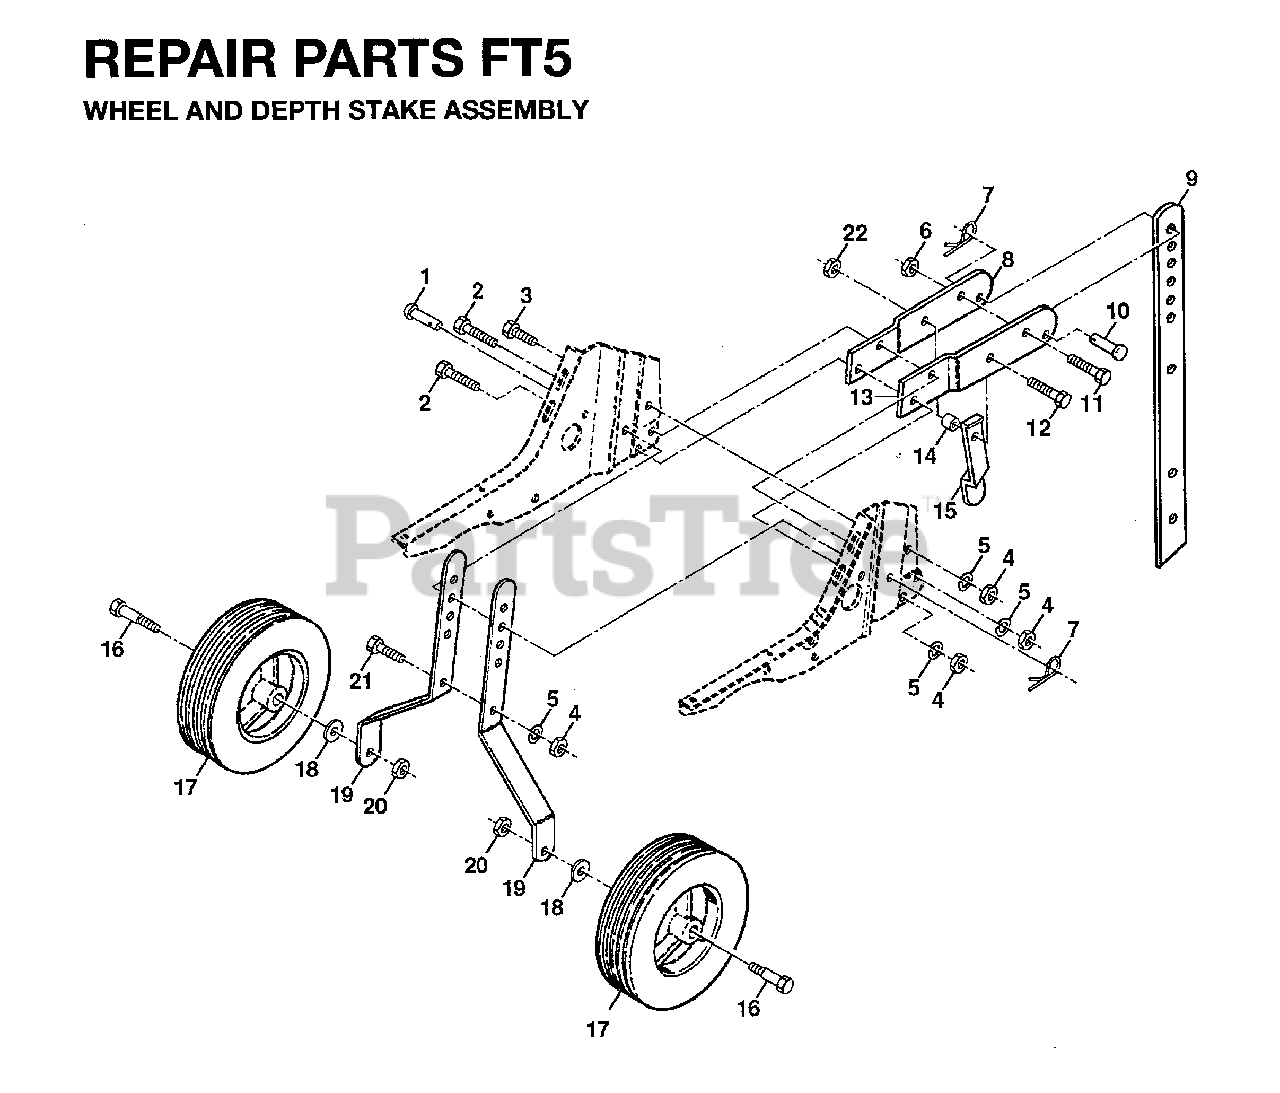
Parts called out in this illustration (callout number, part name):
1	PIN
2	BOLT.5/16-18X1-1/4 FULL.THREAD
3	BOLT
5	LOCKWASHER
6	LOCKNUT
7	SPRING.RETAINER
8	SUPPORT.STAKE.RH.BLACK
9	RP STAKE.DEPTH.13.25.W/9HOLES
11	BOLT
12	HEX BOLT
16	BOLT.SHOULDER
18	WASHER
19	RP BRACKET
20	LOCKNUT
22	NUT.71038.31-18.HEX.NYLOCK
